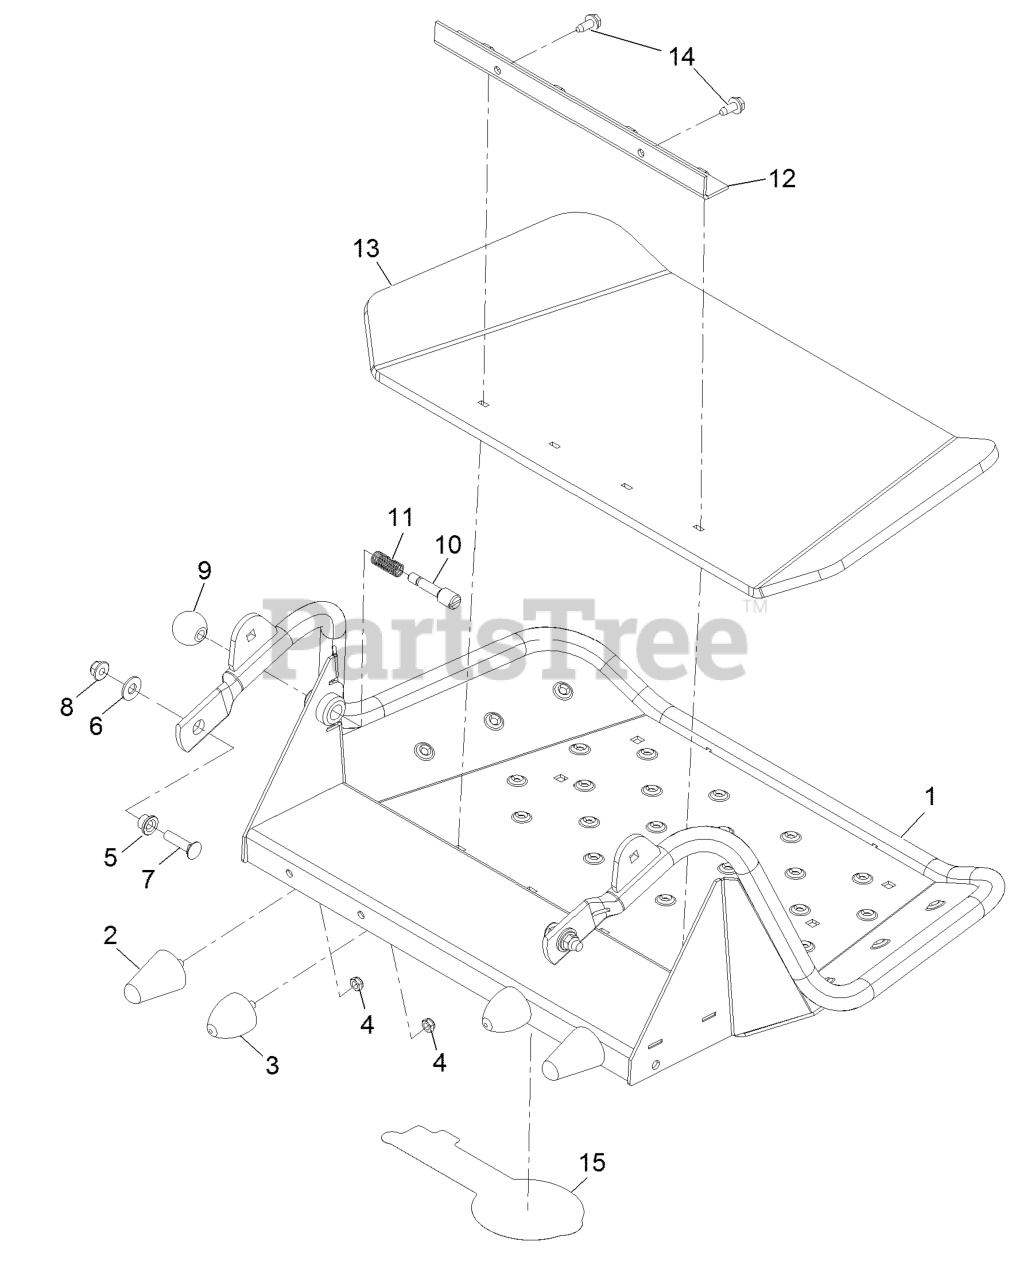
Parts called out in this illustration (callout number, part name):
1	Platform ASM
2	Bumper-Rubber
3	Bumper-Rubber
4	Nut-Nyloc 5/16-18 Thin
5	Bushing-Flanged
6	Washer-3/8 Std
7	Bolt-Carriage 3/8-16 X 1 1/2
8	Nut-Nyloc 3/8-16 Flg
9	Knob-Ball
10	Pin-Latch
12	Clamp-Shield
13	Mat-Platform
14	Screw-HWH 5/16-18 X 3/4 Tf
15	Decal-Exmark Logo
